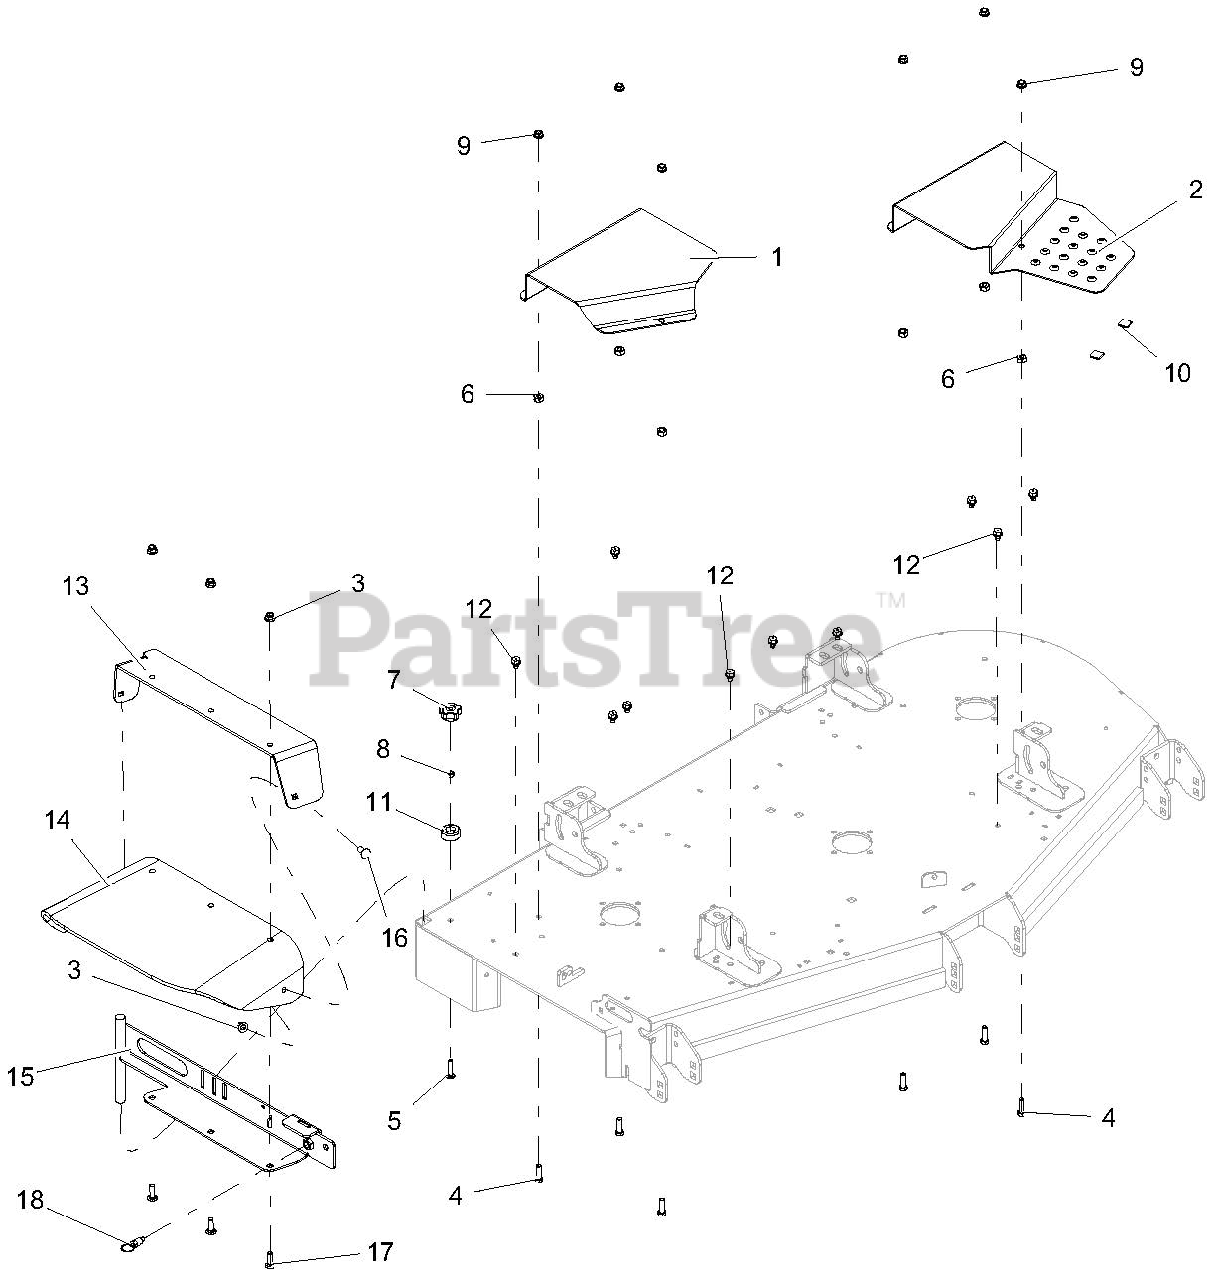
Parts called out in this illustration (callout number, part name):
1	GUARD, 60"-66" RH DECK BELT-RED
2	GUARD, 60" LH DECK BELT-W/STEP-RED
3	NUT-LK-NYL-FLG .38-16 YWZC
4	BLT-HEX .38-16X1.25 GR5 YWZC
5	BLT-RDHDSQNK .31-18X1.50 G5 YWZC
6	NUT-HEAVY HEX .38-16 YWZC
7	KNOB, CLAMPING
8	NUT-LK-CTR .31-18 YWZC
9	@NUT-SPNLK-FLG .375-16 YWZC
11	BUMPER, RECESSED 1.50 X .63 W/.31 HOLE
12	SCR-TAP .38-16X.50 HWH TR YWZ
13	DISCHARGE CHUTE SUPPORT W/SAFETY DECAL-RED
14	CHUTE, RUBBER DISCHARGE
15	WLDMT, 52"-60" DISCH CHUTE MTG-RED
16	BLT-RDHDSQNK .38-16X1.00 G5 YWZC
17	BLT-RDHDSQNK .38-16X1.25 G5 YWZC
18	PULL PIN,.50-13THDX.310 PLNGR
